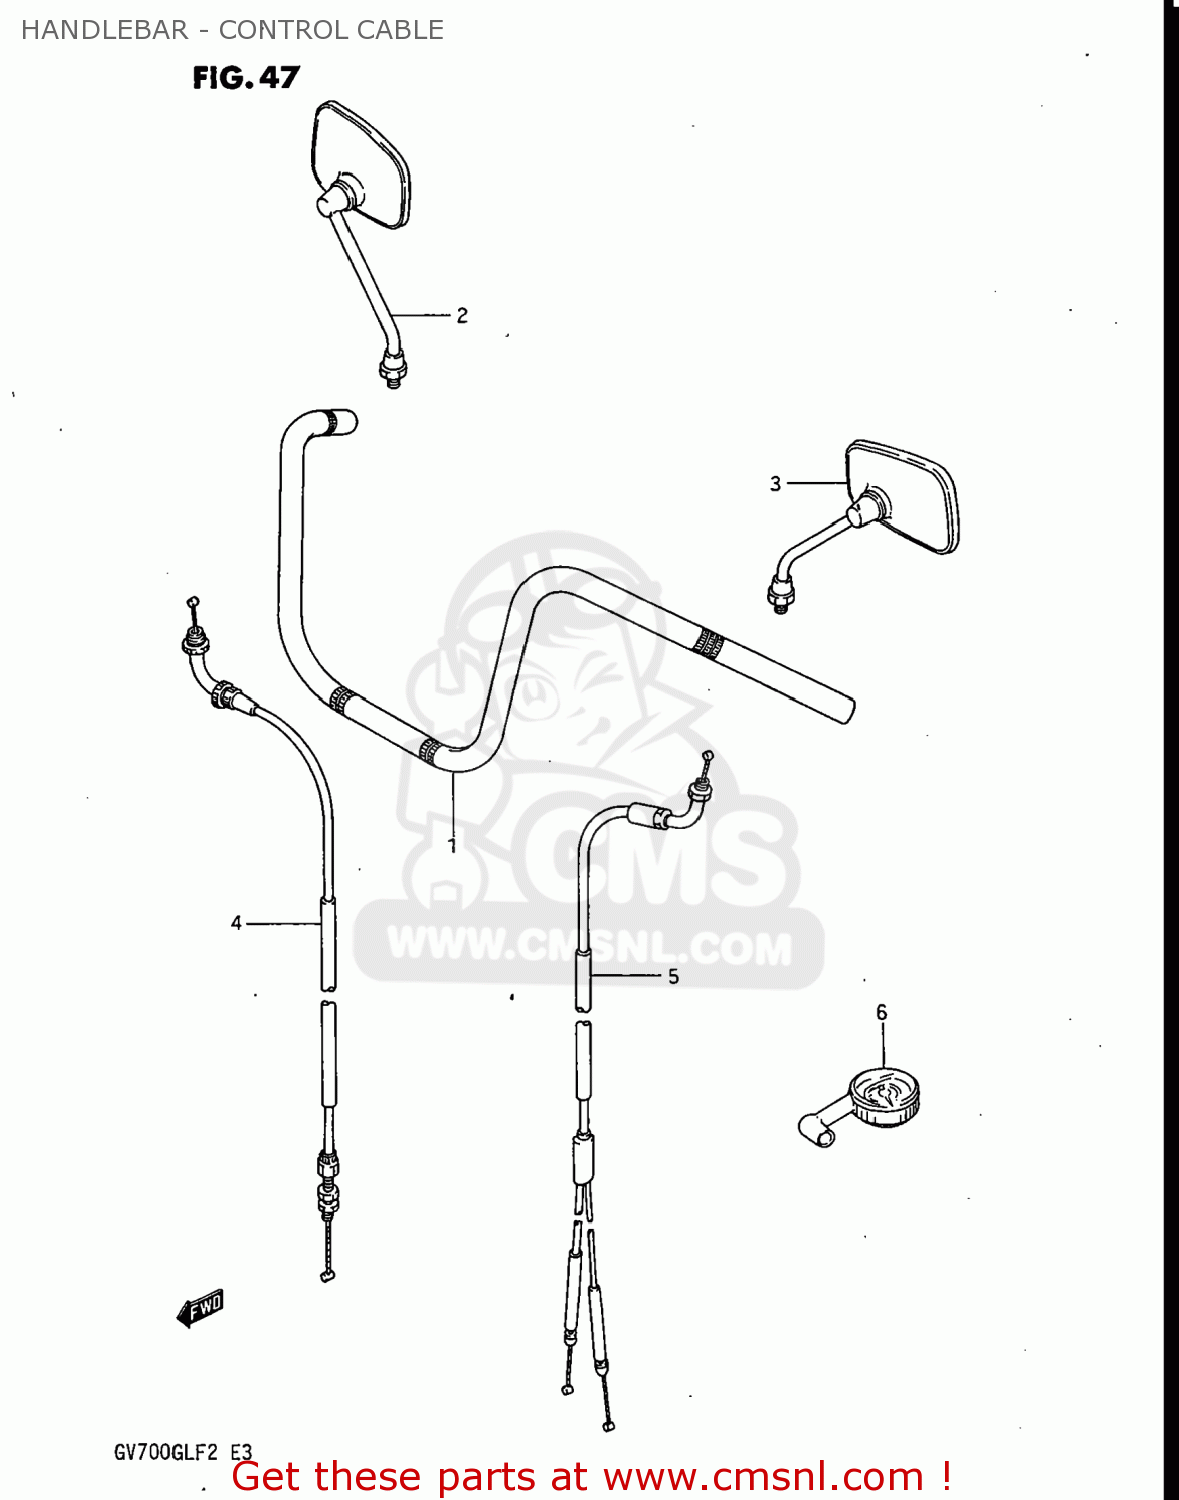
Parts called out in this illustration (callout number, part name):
1	HANDLEBAR
2	MIRROR ASSEMBLY,RIGHT
3	MIRROR ASSEMBLY,LEFT
4	CABLE ASSY,THROTTLE
5	CABLE COMP,STARTER
6	GAUGE ASSY,AIR PRESSURE
